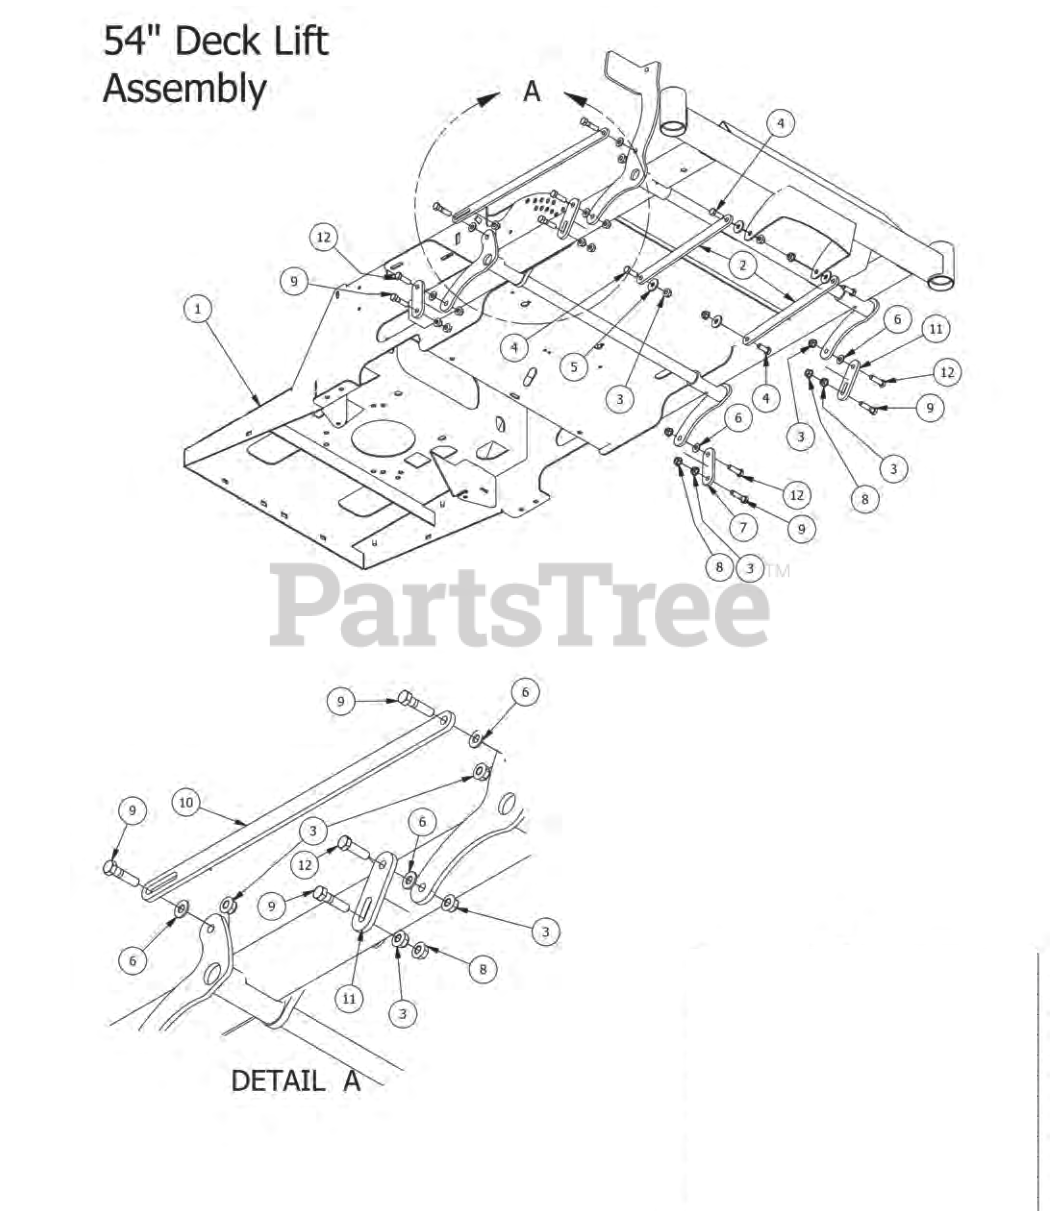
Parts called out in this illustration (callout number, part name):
1	2014 54" MZ Magnum Frame
2	MZ Front Arm
3	3/8" Nylock Flange Nut
4	3/8" x 1" Hex Bolt
5	.390 ID Plastic Washer
6	360 ID Plastic Washer
7	48 Deck Spacer MZ
8	3/8" Flange Nut
9	3/8" x 1 1/2" Hex Bolt
10	MZ Deck Linkage Rod
11	48 Deck Spacer MZ (Front)
12	3/8" x 1 1/4" Hex Bolt
